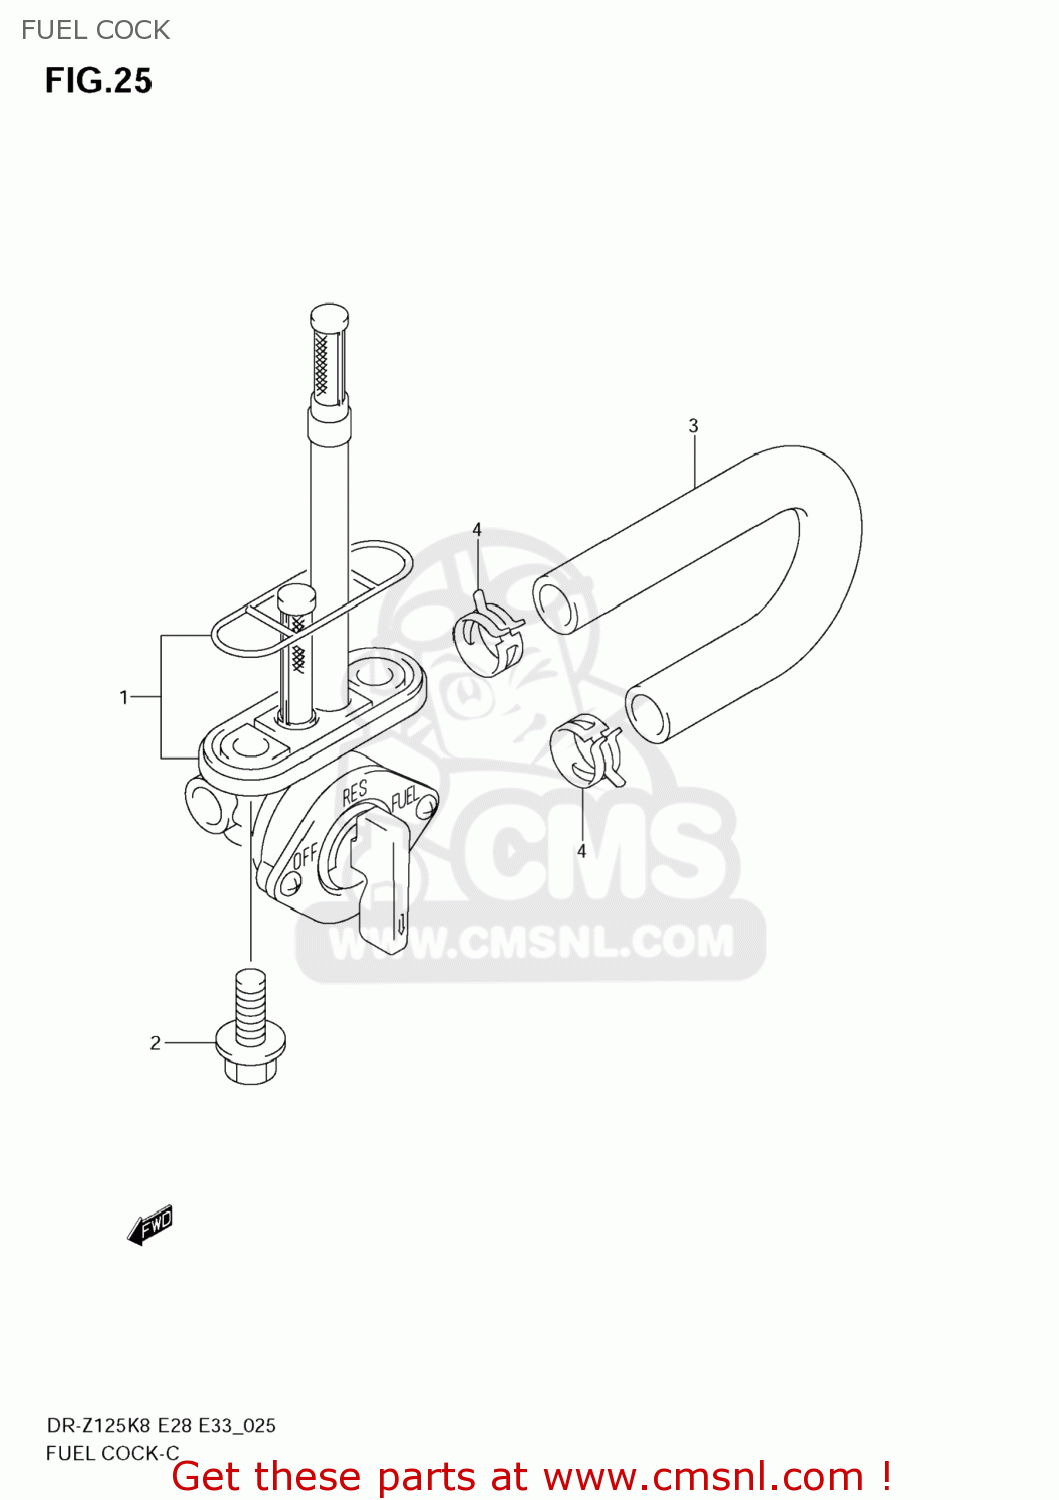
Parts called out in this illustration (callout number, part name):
1	COCK ASSY,FUEL
2	BOLT
3	HOSE,FUEL
4	CLIP
